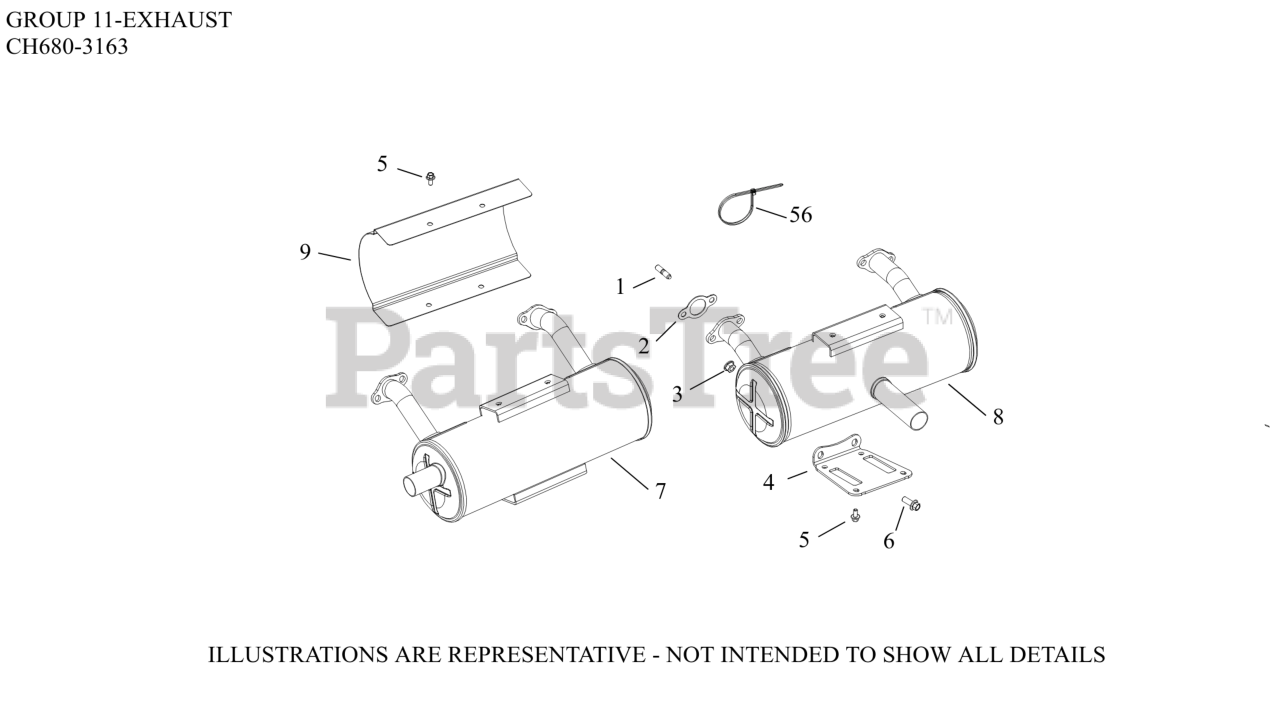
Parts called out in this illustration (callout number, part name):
1	STUD, METRIC EXHAUST
2	GASKET, EXHAUST
3	NUT, FLG M8X1.25
4	BRACKET, MUFFLER
5	SCREW, FLG M6X1.0X12
6	SCREW, FLG M8X1.25X20
7	MUFFLER KIT, CENTER/STRAIGHT
9	SHIELD, ALUM HEAT (LH/CH TWIN)
